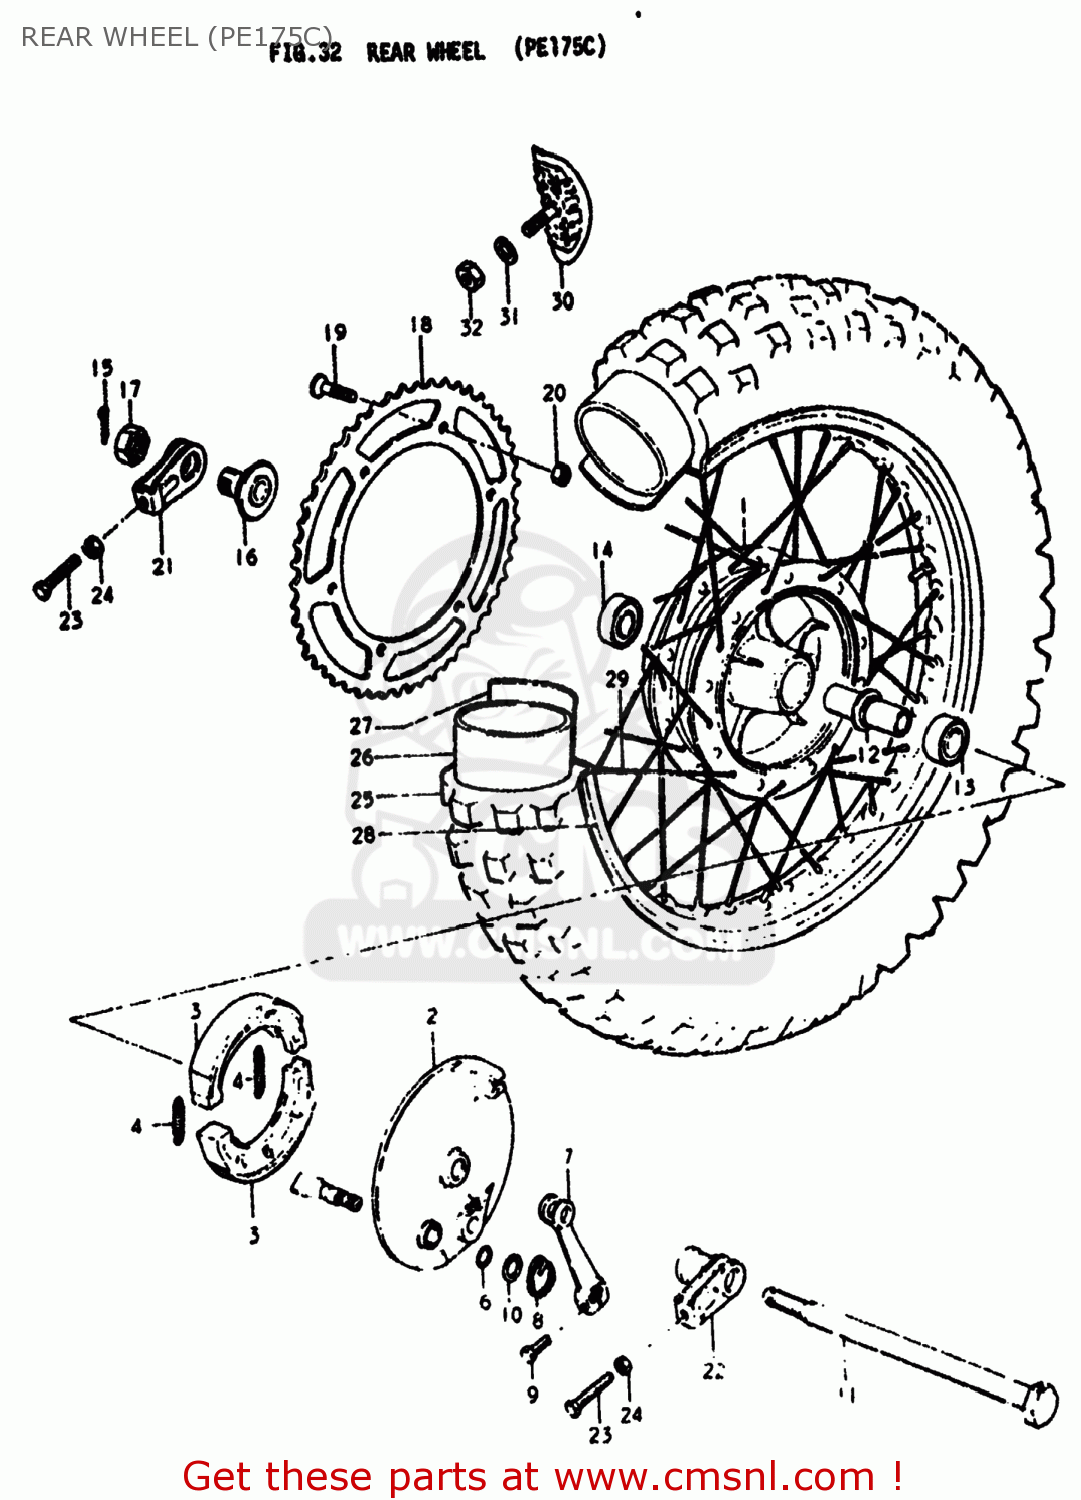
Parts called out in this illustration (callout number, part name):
1	HUB COMP,REAR
2	PANEL,REAR HUB
3	SHOE,BRAKE
4	SPRING(L:34)
5	CAM,FR BRAKE
6	O RING(D:2.5,ID:11.4)
7	LEVER,REAR BRAKE CAM
8	SPRING
9	BOLT
10	WASHER(12.5X20X1)
11	AXLE,REAR
12	SPACER,RR WHEEL HUB BEARING
13	BEARING
14	BEARING
15	COTTER PIN
16	SPACER,CHAIN ADJUSTER
17	NUT
18	SPROCKET,REAR
19	SCREW
20	NUT
21	ADJUSTER,CHAIN,L
22	ADJUSTER,CHAIN
23	BOLT(8X40)
24	NUT
25	TIRE
26	TUBE ASSEMBLY,WHEEL,INNER
27	PROTECTOR,WHEEL,INNER
28	RIM,REAR WHEEL
29	SPOKE SET,REAR
30	STOPPER,BEAD
31	WASHER
32	NUT
